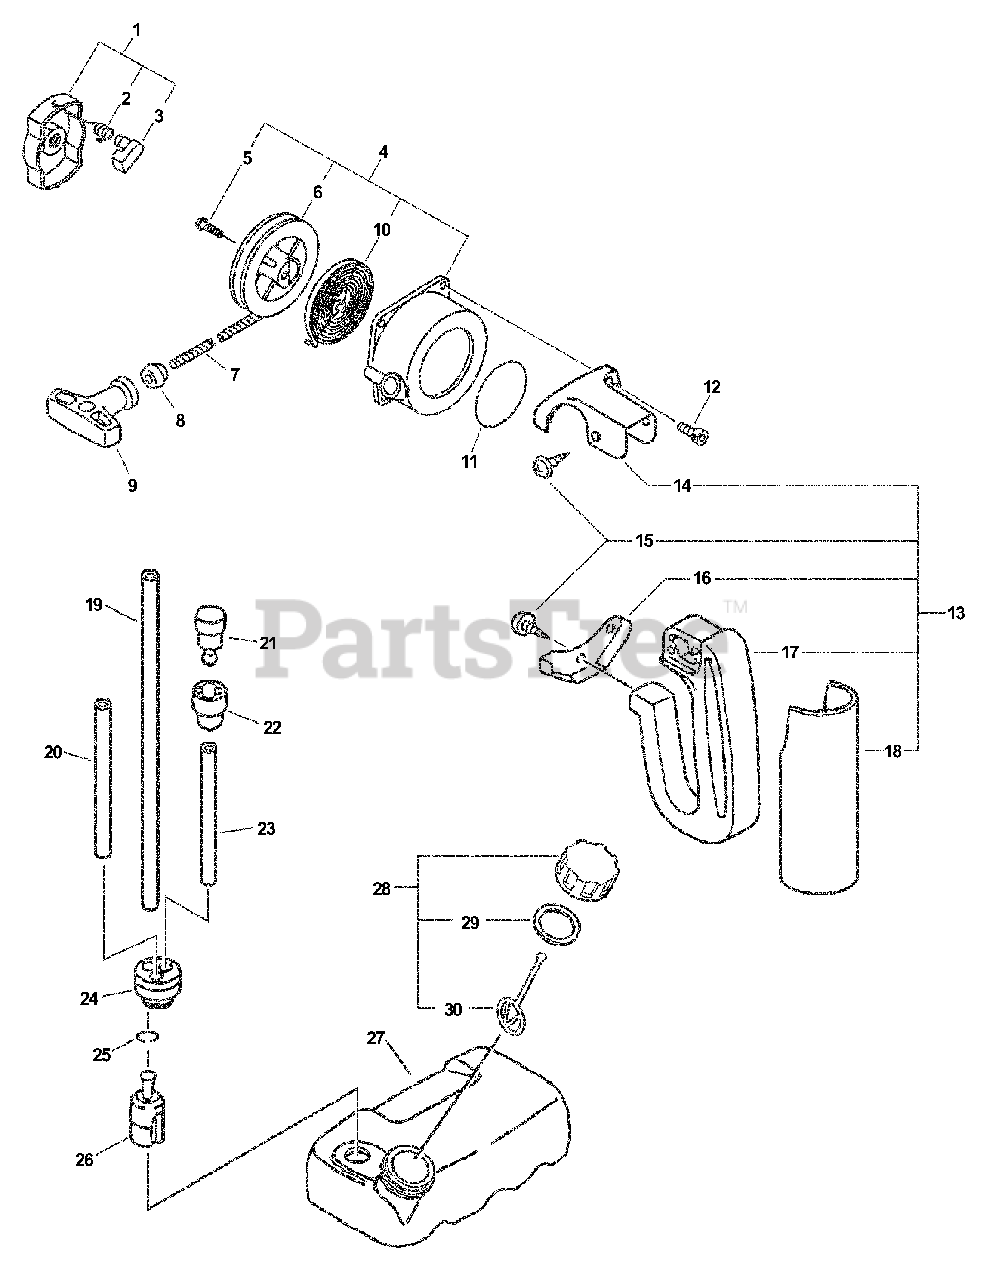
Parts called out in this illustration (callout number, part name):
1	STARTER PAWL ASSY
2	SPRING, RETURN
3	PAWL, STARTER - BLACK
4	STARTER ASSY
6	REEL, ROPE
7	ROPE, STARTER - 3.5X960
8	GUIDE, ROPE
9	GRIP, STARTER
10	SPRING, REWIND
11	LABEL - ECHO
12	SCREW - 4X18
13	SIDE HANDLE ASSY
14	BRACKET, HANDLE - UPPER
15	SCREW - 5X16 -- TAPPING
16	BRACKET, HANDLE - LOWER
17	HANDLE - REAR
18	GRIP, HANDLE
19	PIPE - 3X6X200 -- BLACK
20	PIPE - 3X6X100 -- CLEAR
21	VENT, FUEL TANK
22	COVER, VENT
23	PIPE - 3X6X100 -- BLACK
24	GROMMET
25	CLIP - 6.5
26	FILTER, FUEL
27	TANK, FUEL
28	CAP ASSY - ORANGE
29	GASKET, CAP
30	CONNECTOR, CAP
